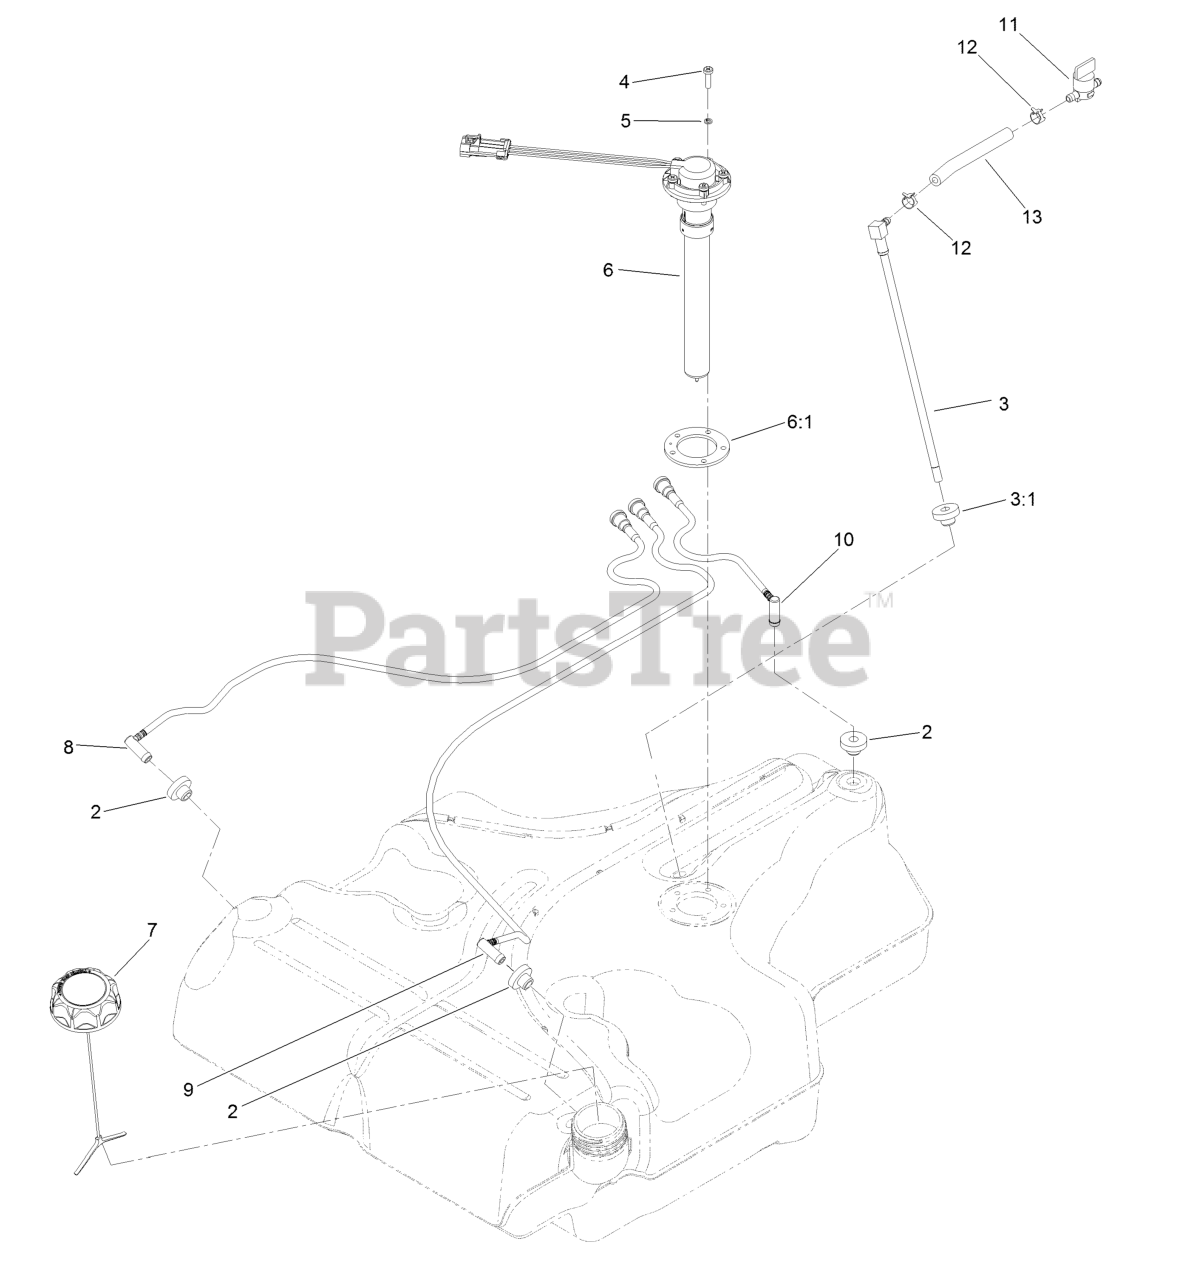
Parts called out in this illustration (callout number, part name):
2	BUSHING
3	FUEL LINE KIT (WITH GROMMET)
3:1	BUSHING
4	SCREW-PAN
5	WASHER-LOCK
6:1	GASKET-SENDER, FUEL
7	CAP-FUEL, RATCHETING
8	RH VENT LINE KIT (WITH GROMMET)
9	LH VENT LINE KIT (WITH GROMMET)
10	REAR VENT LINE KIT (WITH GROMMET)
11	VALVE-FUEL
12	CLAMP-HOSE
13	HOSE-FUEL
